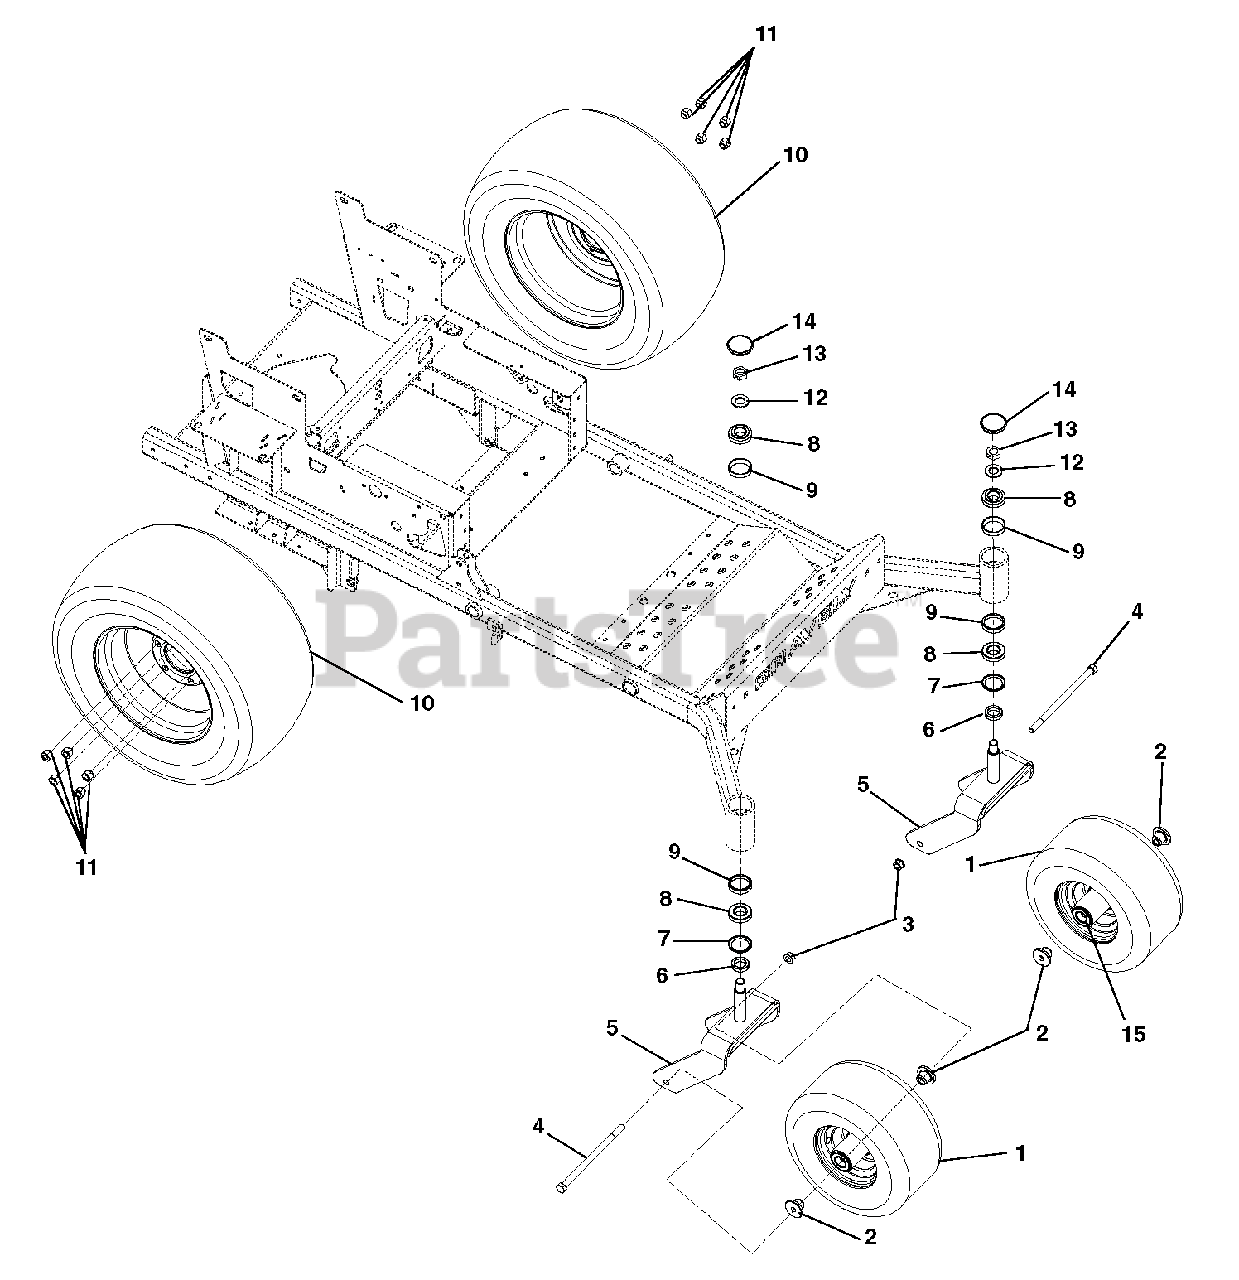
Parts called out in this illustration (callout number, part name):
1	TIRE/WHEEL ASM, 13X6.50-6
2	SPACER, FRONT WHEEL
3	@NUT-LK-NYL-FLG .50-13 YWZC
4	@BLT-HEX .50-13X9.00 GR5 YWZC
5	CASTER FORK WMT - RED
6	SPCR, 1.258ID X 1.750OD X.550
7	SEAL, OIL 1.75 X 2.332 X .312
8	BRG-CONE 1.25X.66
9	BRG-CUP 2.328X.465
10	TIRE/WHEEL ASSY, 23X10.00-12
11	WHEEL NUT .500-20 YZ
12	@WSHR-FL-STL.812X2.00X.148YWZC
13	NUT-JAM CTRLK .75-16 YWZC
14	CAP, DUST
15	BRG, 25MM ID X 52MM OD X 15MM
